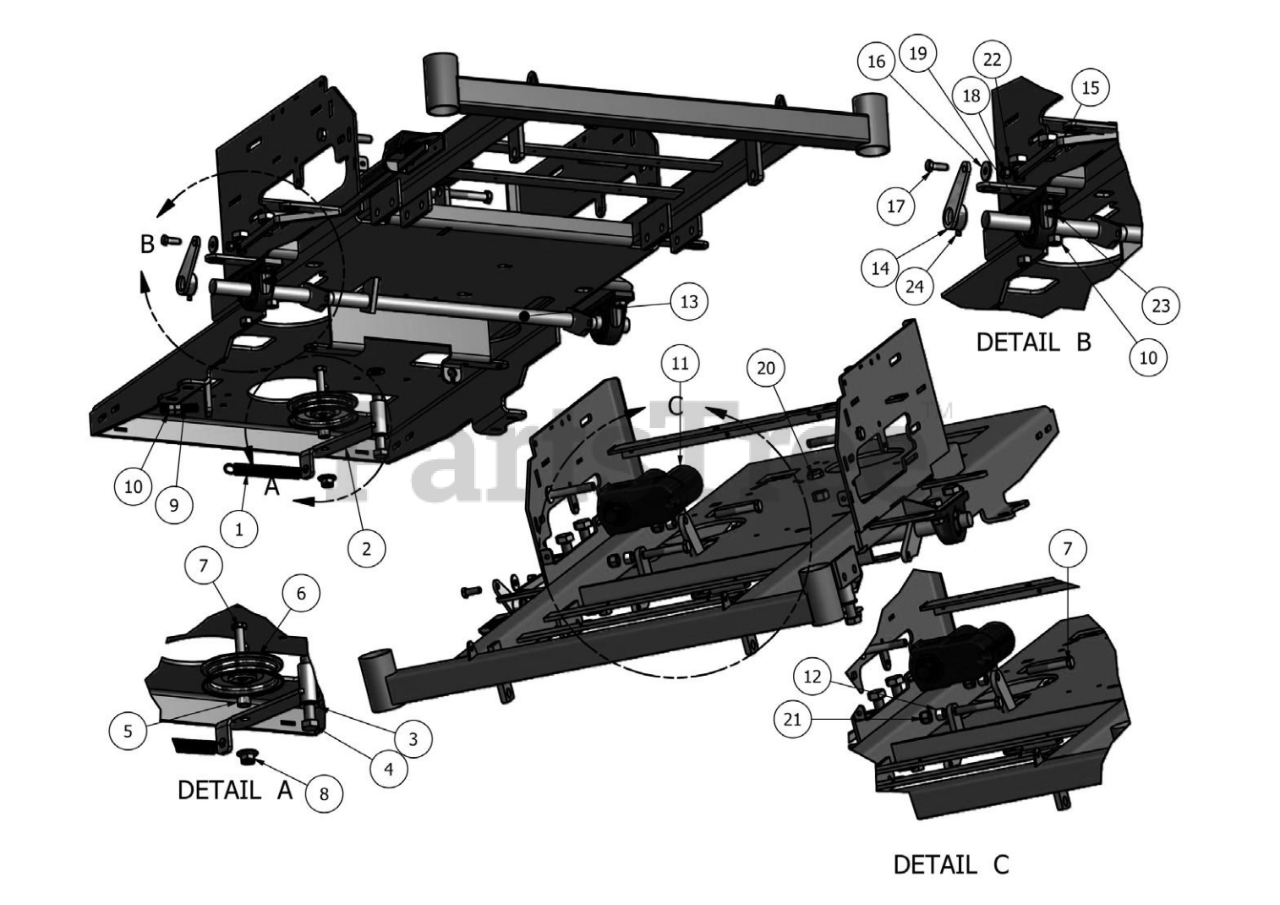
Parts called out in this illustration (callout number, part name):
1	Pump Idler Spring
2	Pump Idler Bracket
3	.635 ID Plastic Washer
4	5/8" x 4" Hex Bolt
5	1/2 x 1/2 Spacer
6	4 3/4" Idler Pulley
7	1/2-13 x 2-3/4 GR 5 Hex
8	1/2-13 Nylon Flange Nut-Orange
9	1/2-13 x 2-1/2 All Thd Stud
10	1/2" Hex Nut
12	1/2 x 1/2 Spacer
13	ZT Actuator Bar
14	Height Indicator Tab (component)
15	Height Indicator Bar
16	.390 id x .750 od x .062 Nylon Washer
17	3/8" x 1" Hex Bolt
18	3/8 Nylock Nut
19	Pillow Block Bearing
20	5/8" Nylock (1/2 Jam)
21	1/2" Nylock Nut
22	5/8" x 1 1/2" Grade 8 Bolt
23	1/2" Lock Washer
24	1/4" x 3/4" Set Screw
